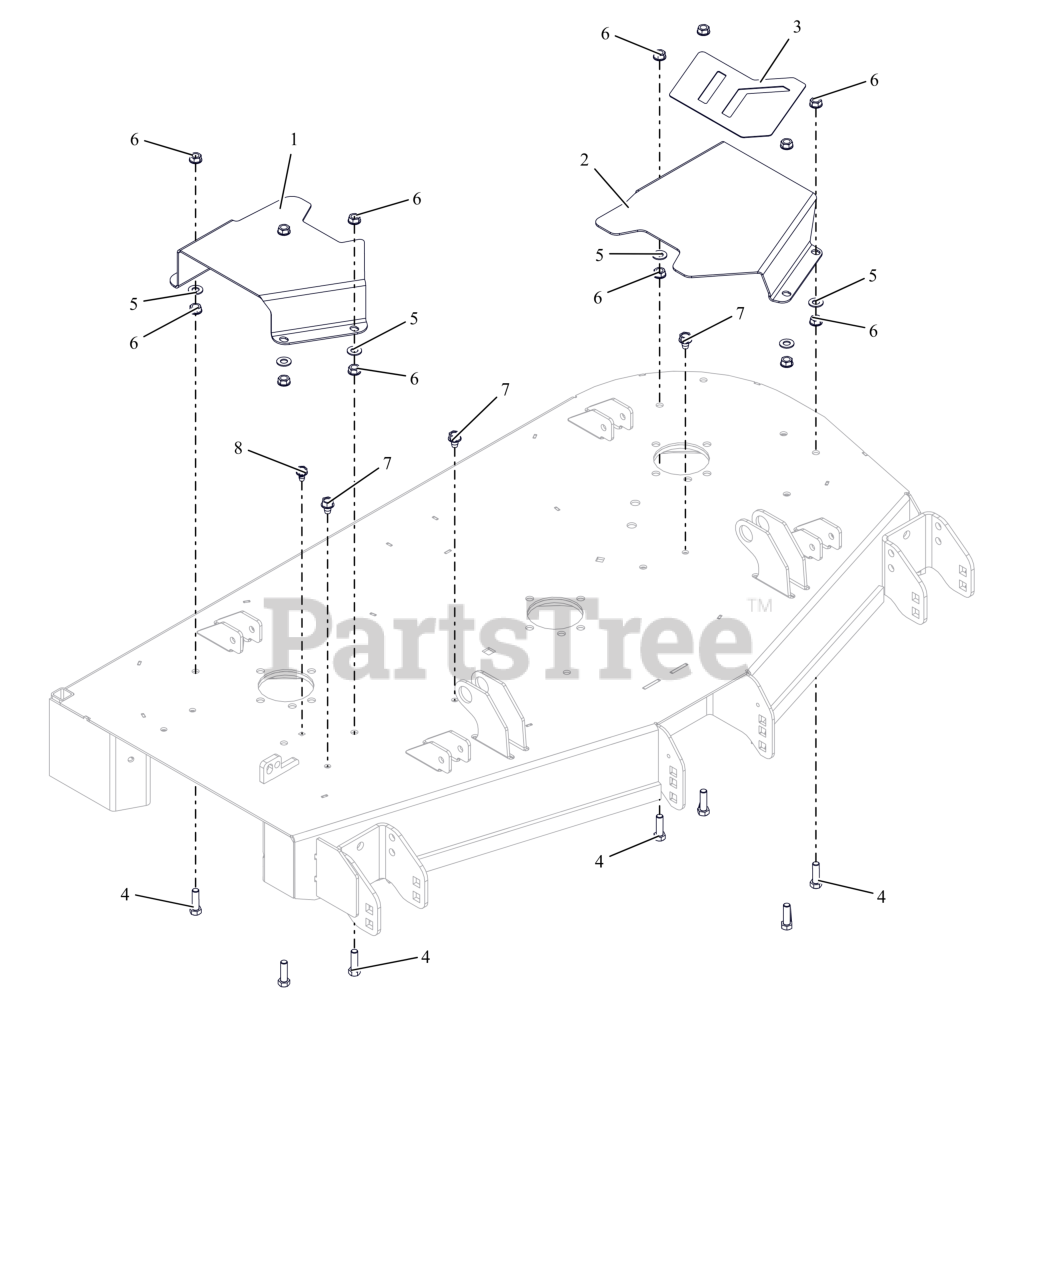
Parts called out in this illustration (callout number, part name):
1	COVER, BELT 48" RIGHT
2	COVER, BELT 48" LEFT
3	GRIP TAPE 48 BELT COVER
4	BLT, HEX .38-16X1.25 G5 ZCC
5	WSHR,FLT .406X.812X.065 ZCC
6	NUT, SPNLK-FLG .38-16 G5 ZCC
7	SCR,TAP .375-16X.50 HWH TR ZCC
8	SCR,TAP .312-18X.50 HWH TR ZCC
